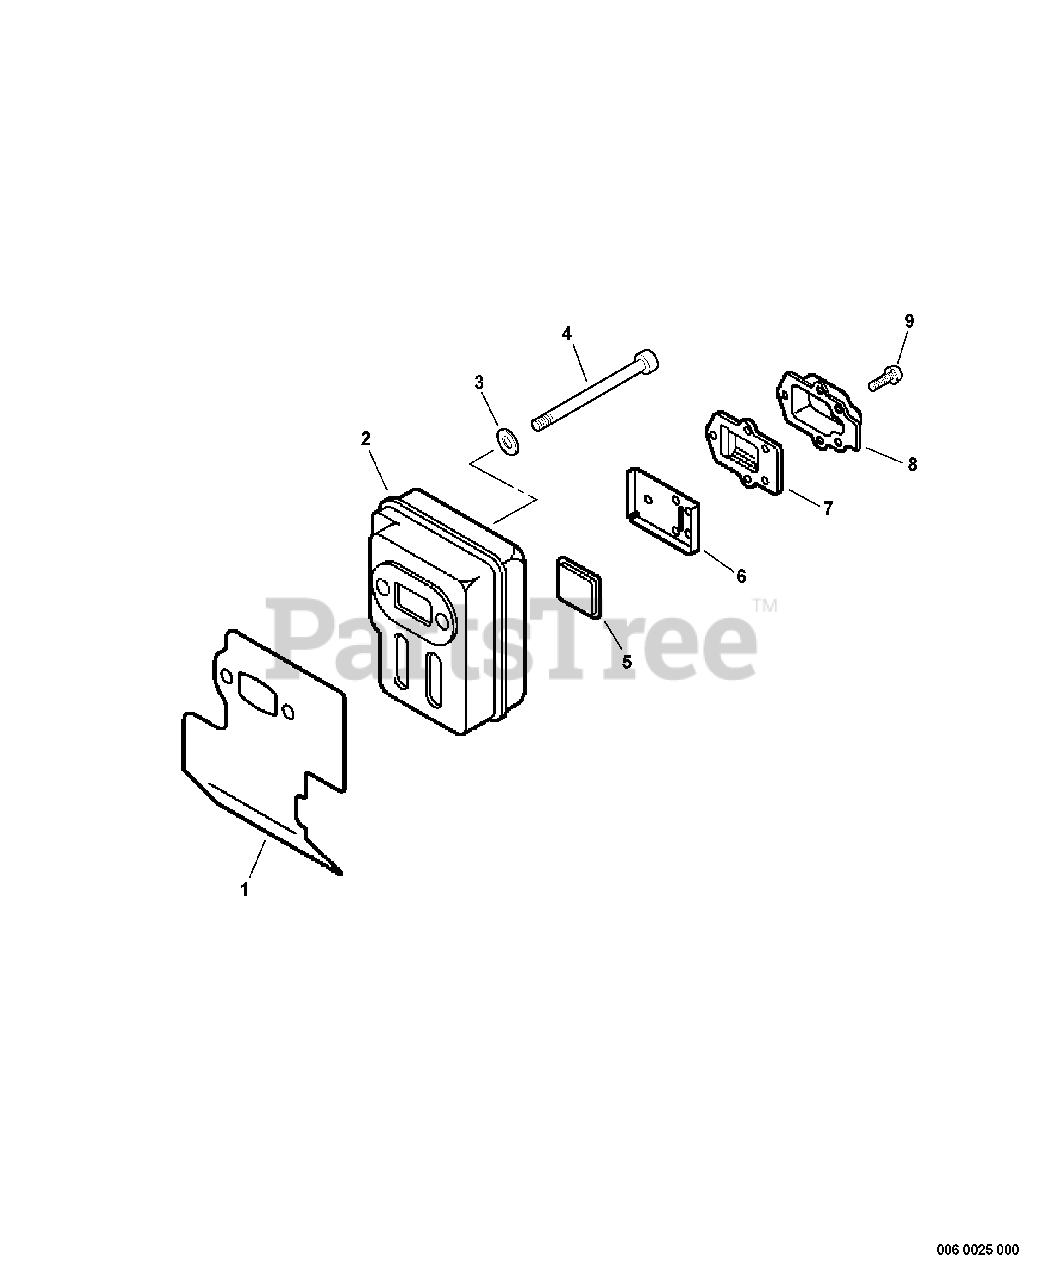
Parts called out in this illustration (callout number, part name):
1	HEAT SHIELD, EXHAUST
2	MUFFLER
3	WASHER 5.5×12×0.8
5	SCREEN, SPARK ARRESTER
6	GASKET, EXHAUST
7	GUIDE, EXHAUST
8	OUTLET, EXHAUST
9	SCREW 4×12
